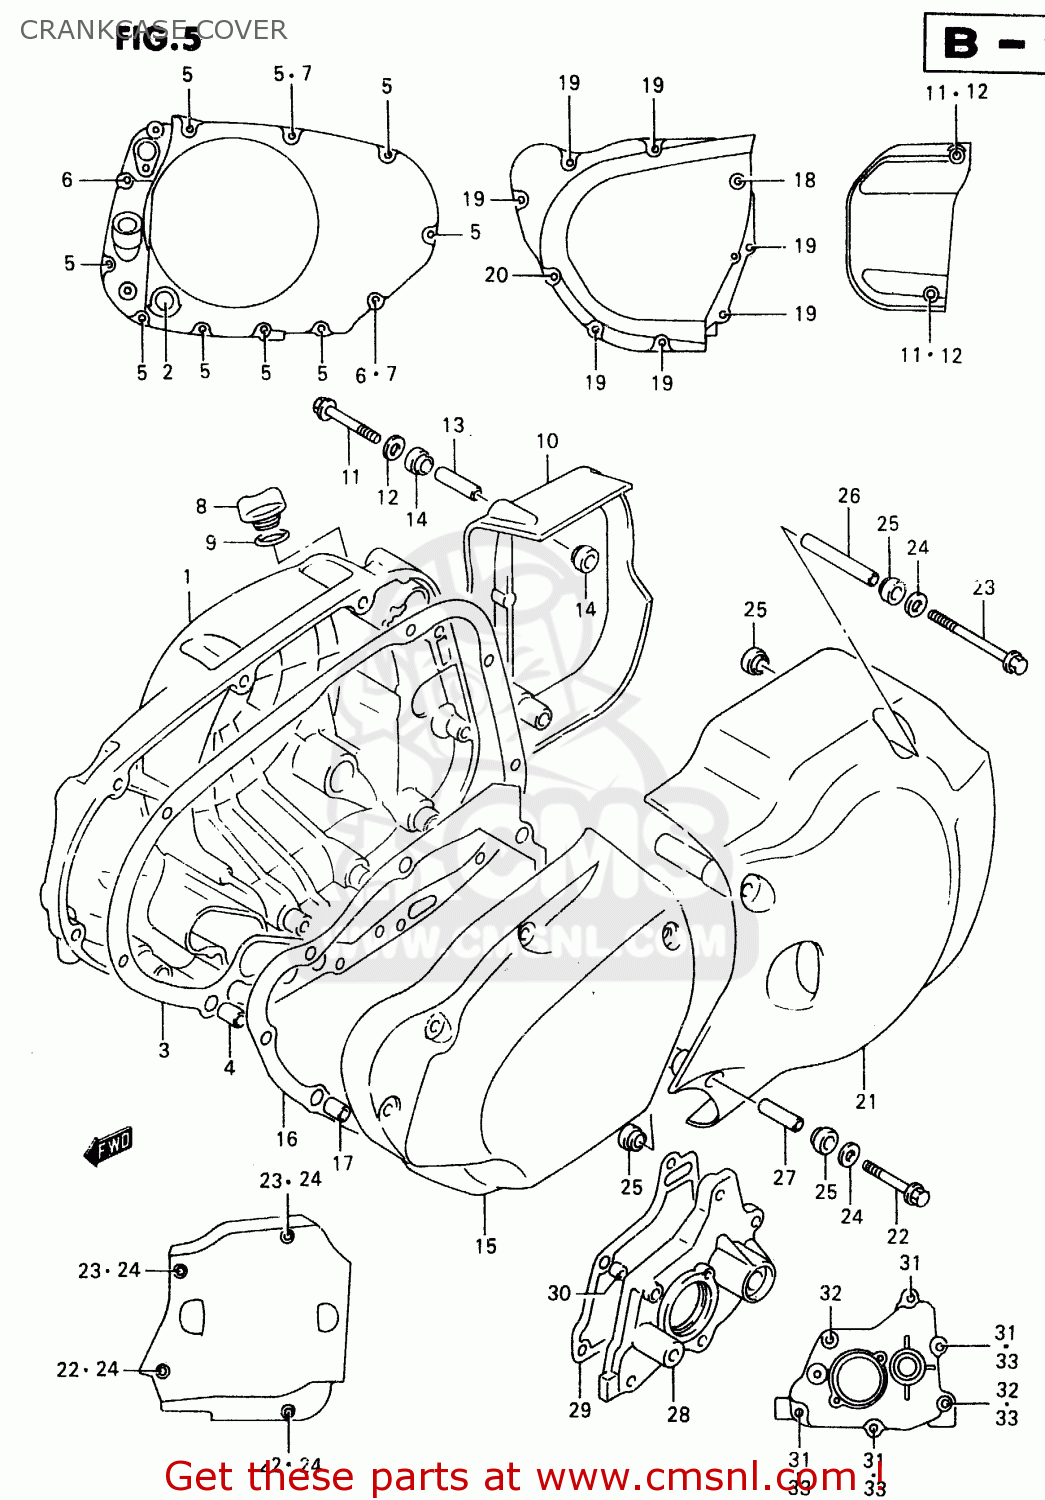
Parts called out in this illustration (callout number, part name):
1	COVER,CLUTCH
2	LENS,OIL LEVEL CHECK
3	GASKET,CLUTCH COVER (NAS)
4	PIN
5	BOLT
6	BOLT
7	GASKET(5.8X11X1.2) (NAS)
8	PLUG(20X10)
9	O RING(D:3.1,ID:16.8)
10	COVER,CLUTCH RR
11	BOLT
12	WASHER(6.5X14X1.6)
13	SPACER(6.5X9X31.5)
14	WASHER(8.7X16X5)
15	COVER,GENERATOR
16	GASKET,GENERATOR COVER (NAS)
17	PIN(8.4X11X20)
18	BOLT
19	BOLT
20	BOLT
21	COVER,SECONDARY DRIVE UNIT
22	BOLT
23	BOLT
24	WASHER(6.5X14X1.6)
25	WASHER(8.7X16X5)
26	SPACER(6.1X9X55.9)
27	SPACER(6.5X9X26)
28	COVER,GEAR SHIFT
29	GASKET,GEAR SHIFT COVER (NAS)
30	PIN
31	SCREW
32	BOLT
33	GASKET(5.8X11X1.2) (NAS)
